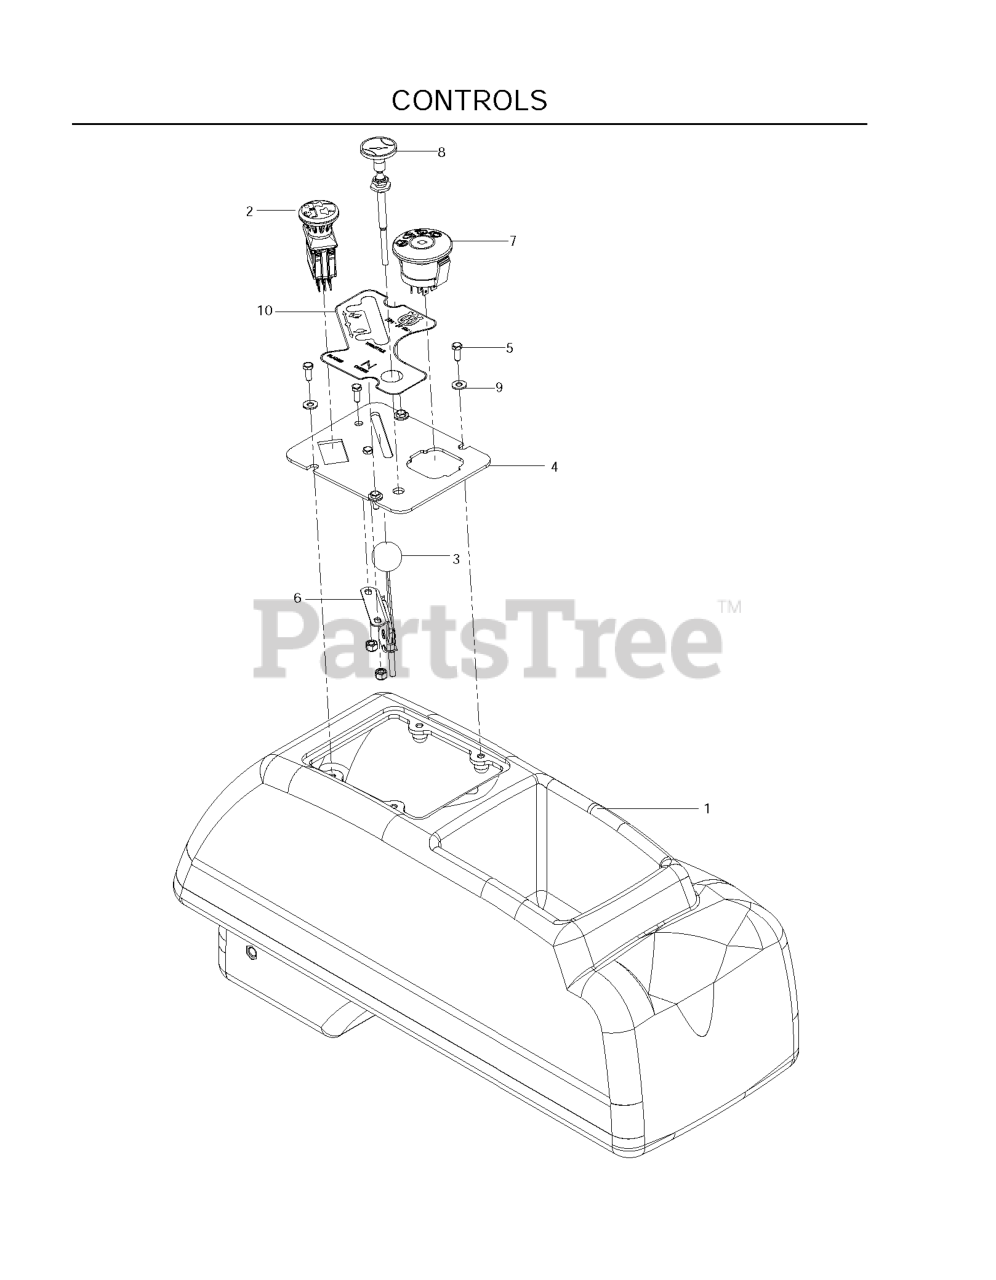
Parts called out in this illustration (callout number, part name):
1	FENDER CONSOLE
2	RP SWITCH.PTO.TERMINAL.STD.RED
3	THROTTLE CABLE
4	CONSOLE PLATE, BLACK
5	HCS #10-24 X 1/2
6	NUT 10-24 NYLOC
7	RP IGNITION SWITCH
8	CHOKE CONTROL
9	WASHER #10
10	DECAL, CONSOLE
